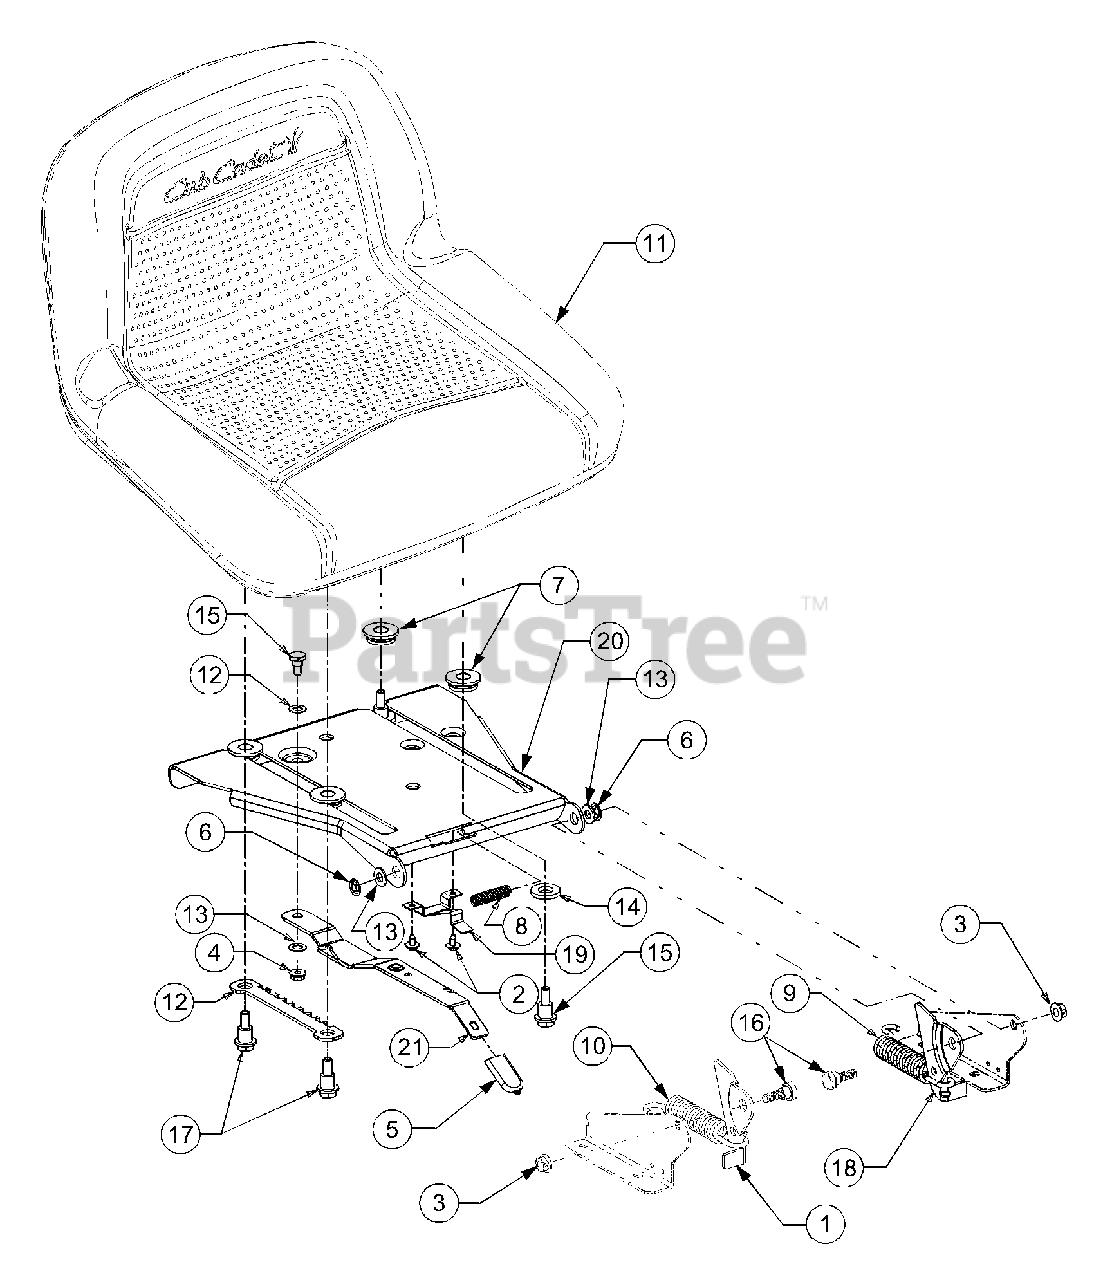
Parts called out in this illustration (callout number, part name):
1	Bracket, Seat Lift
2	Screw, #10-16, 0.375
3	Nut, Nylon Lock, 5/16-18, Gr5
4	Nut, Nylon Lock, 1/4-20
5	Grip, Seat, Adjustment (Yellow)
6	Nut, Speed, .3125 ID
7	Spacer, Seat, Adjustment
8	Spring, Compression .41 OD x 1.50
9	Spring, Extension, .80 Dia x 4.2 Lg.
10	Spring, Extension, .815 Dia x 4.4 Lg.
11	Seat, Mid-back, V-1480
12	Selector, Seat, Adjustment
13	Washer, Flat, .344 x .688 x .065
14	Washer, Flat, .531 x 1.062 x .134
15	Screw, Shoulder, .340 x .285, 1/4-20
16	Shoulder, Screw .437 x .286 Lg
17	Screw, Shoulder, .50 x.925, 3/8-16
18	Bracket, Seat Lift
19	Stop, Seat, Adjustment
